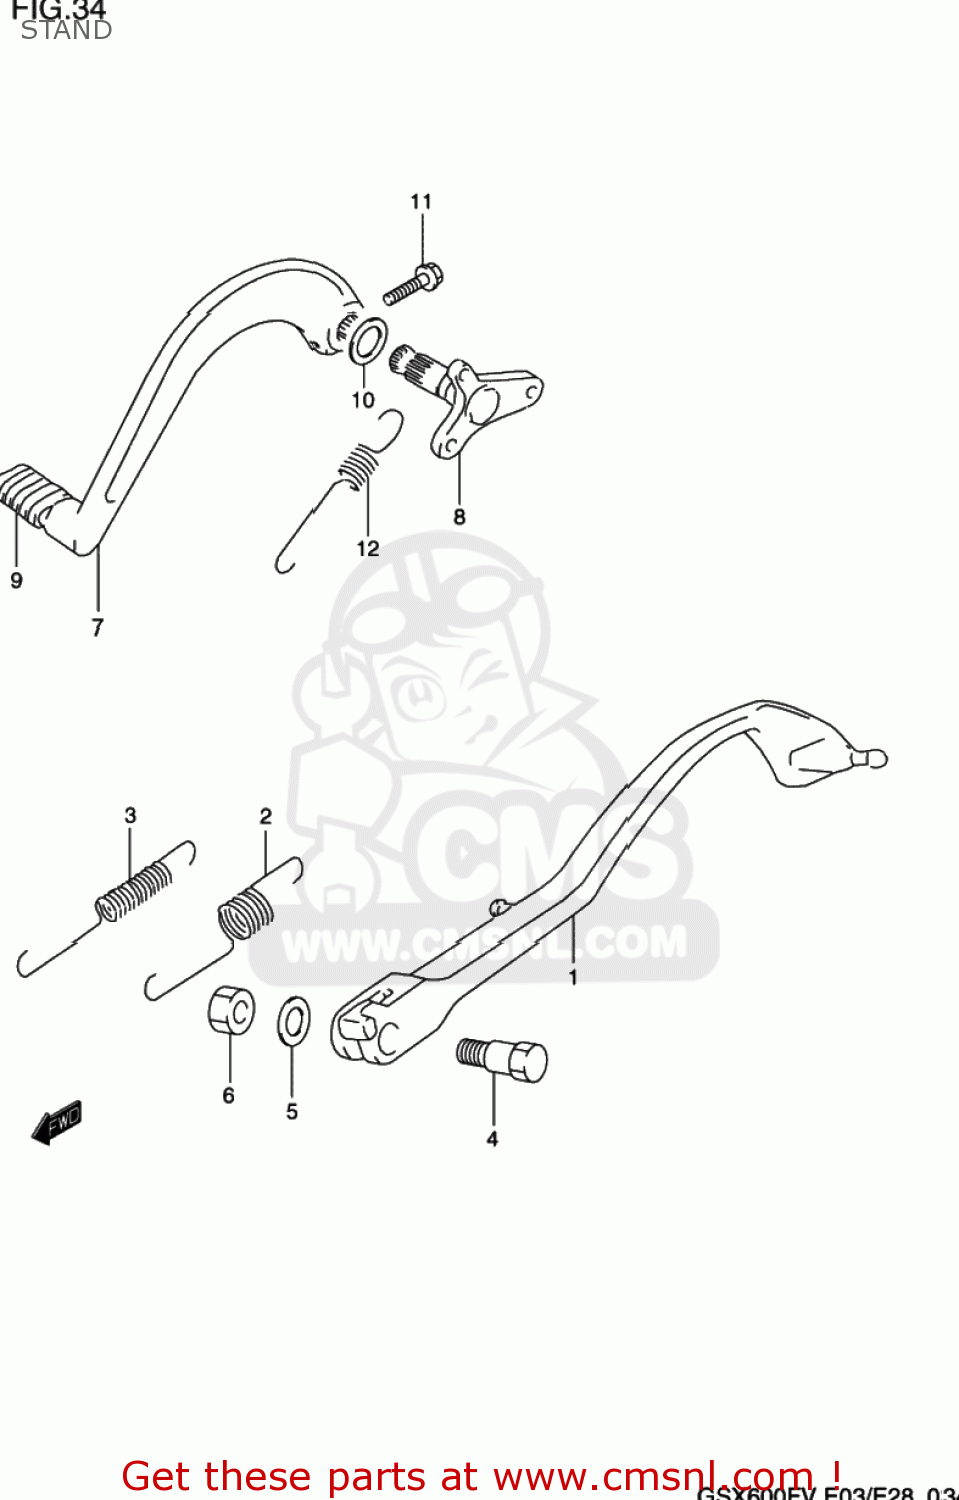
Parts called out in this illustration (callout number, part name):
1	STAND,PROP
2	SPRING
3	SPRING
4	BOLT(10X38)
5	SHIM
6	NUT
7	PEDAL,BRAKE
8	BOSS,BRAKE ROD
9	RUBBER,BRAKE PEDAL
10	WASHER,BRAKE PEDAL
11	SCREW
12	SPRING
